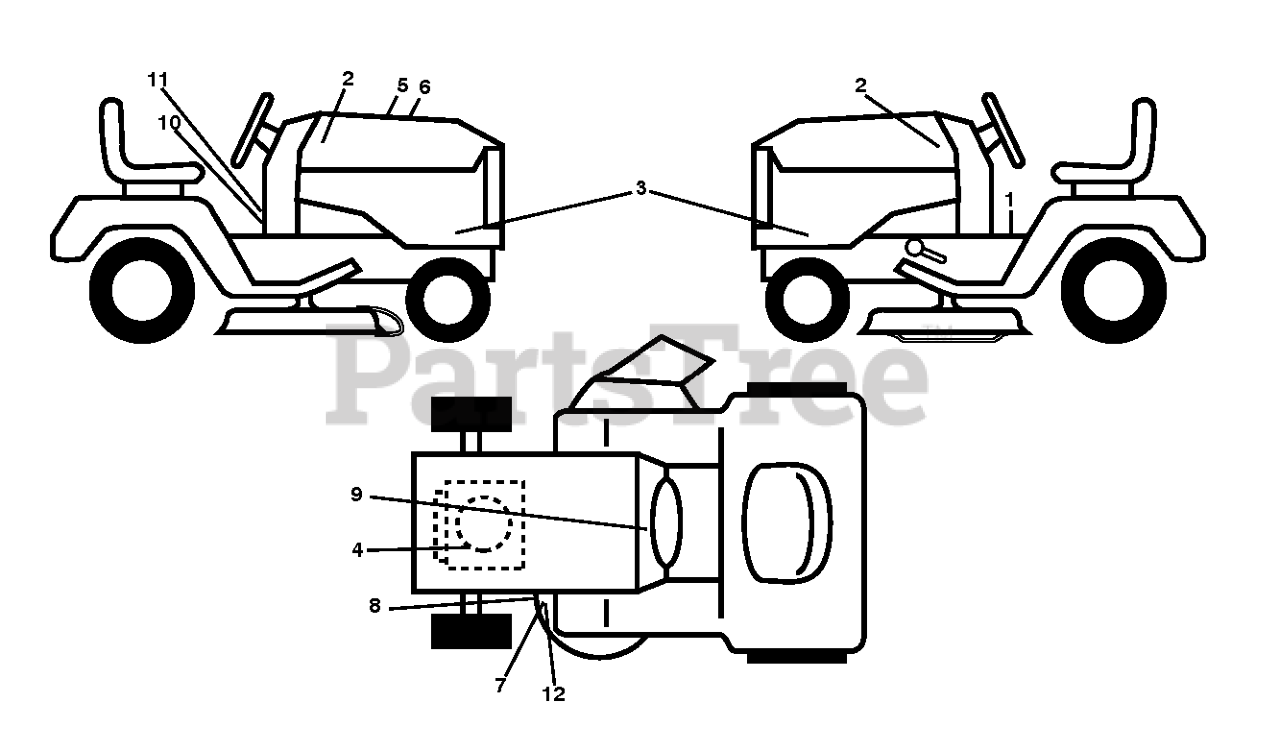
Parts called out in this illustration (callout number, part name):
1	DECAL.FENDER.WARNING
2	DECAL.BADGE.170MM.TEXTLOGO.
3	DECAL.SDPNL.YTH26V54.HUSQ.X668
4	DECAL.ENG.BS.26 HP.PROF.278955
5	DECAL.WARNING.CUST.RESP.E85.
6	DECAL.RPL.BSM44.PRDF.TLW.54.K4
7	DECAL.WARN.KEEP.HAND.AWAY
8	DECAL.MOWER
9	DECAL BTRY SYMBOLS
10	DECAL, WARNING SPARK ARRESTOR
11	LABEL.EMISS.CA.HUSQ/LOWES.2011
12	DECAL.MOWER.SCH.48/54
